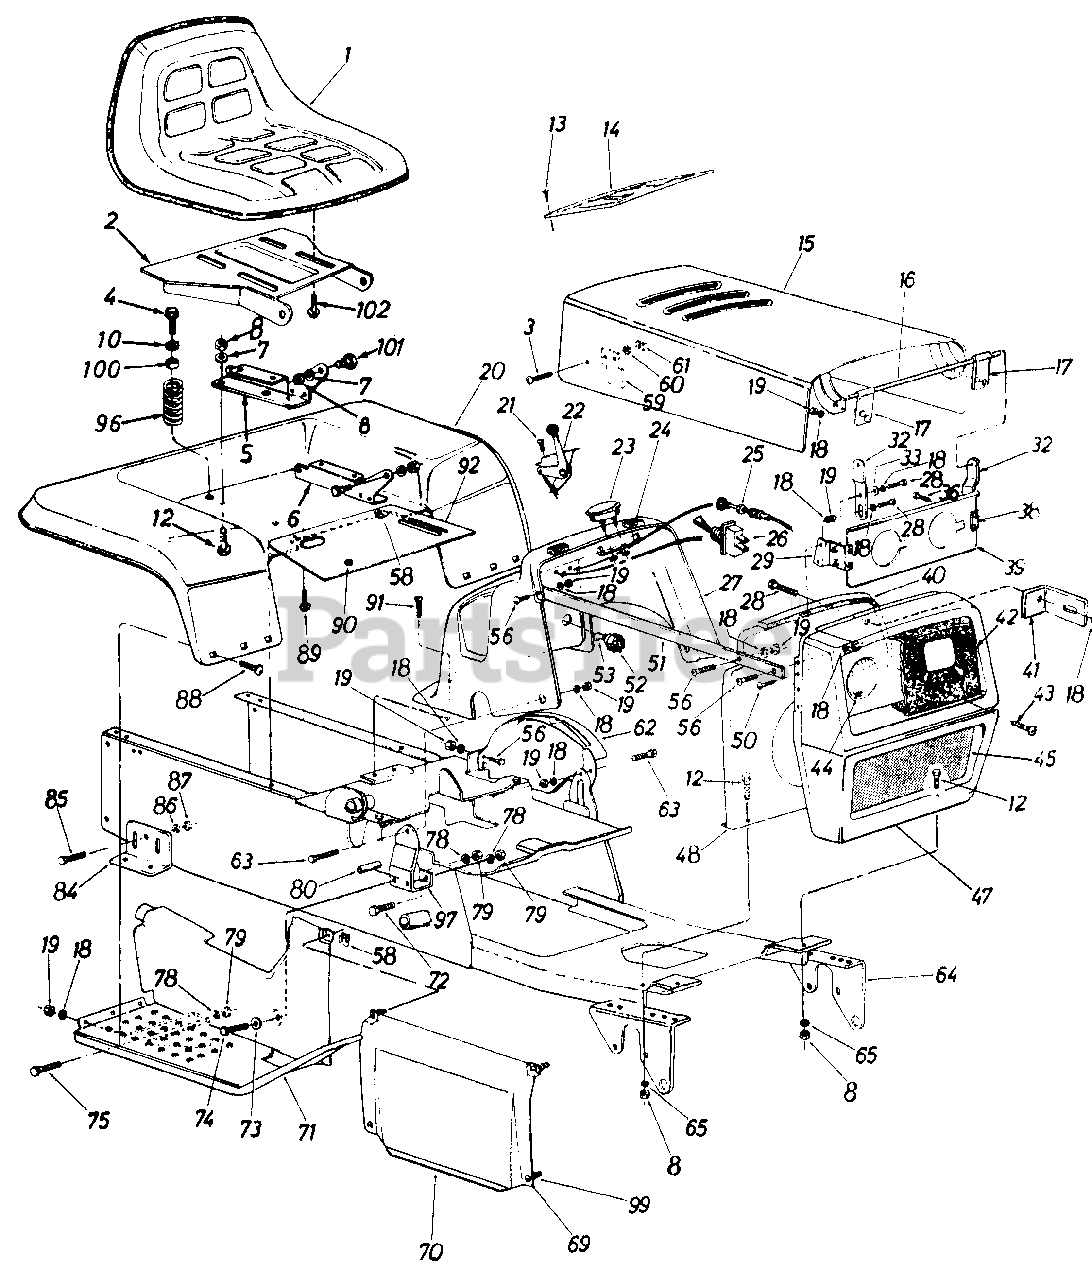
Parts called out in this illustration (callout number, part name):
1	Seat Ass'y.
2	Seat Pivot Brkt.
3	Truss Hd. Mach. Scr. #10-24 x .38" Lg.
4	Hex Wash. Hd. Self-Tap Scr. 5/16-18 x 1.75" Lg.
8	Hex Nut 5/16-18 Thd.
10	Fl-Wash 344" I.D. x .875" O.D
12	Hex Scr. 5/16-18 x .75" Lg.
13	Self-Tap Oval Hd. Scr. 1/2" Lg.
14	Dash Panel Cover
15	Hood Ass'y.
16	Hinge Rod
17	Hood Hinge Ass'y.
18	L-Wash. 1/4" I.D.
19	Hex Nut 1/4-20 Thd.*
20	Rear Fender
21	Fl-Hd. Truss Scr. #10 x .62" Lg.
22	Throttle Control
23	Ammeter
24	Rubber Bumper
25	Choke Control
26	Light Switch
27	Dash Panel
28	Hex Scr. 1/4-20 x .62" Lg.
29	Hood Support Brkt. Ass'y. R.H.
36	Hex Scr. 1/4-20 x .38" Lg.
38	Hood Support Brkt. Ass'y. L.H.
41	Heat Shield Brkt.
42	Head Lamp Bezel
43	Truss Mach. Scr. #10-24 x .50"
44	Head Lamp
45	Grille Screen
50	Truss Mach. Scr. 1/4-20 x .75" Lg.*
51	Grille Strap
52	Ignition Switch
53	Ignition Key
56	Hex Scr. 1/4-20 x .75/1 Lg.
58	Clip-On Receptacle
59	Hood Spring
60	L-Wash. #10
61	Hex Nut #10-24
62	Speed Control Guide
63	Truss Mach. Scr. 1/4-20 x .75"Lg.
64	Frame Ass'y.
65	Bell-Wash. 5/16 I.D.
69	1/4-Turn Stud
70	Hood Lower Side Panel
71	Foot Step Panel Ass'y. R.H.
72	Hex Scr. 3/8-16 x 1.00" Lg.Grade 5
73	Fl-Wash. .385 I.D. x .62 O.D.
74	Hex Scr. 3/8-16 x 3.00 Lg.
75	Hex Scr. 3/8-16 x 1.00" Lg.Grade 5
78	L-Wash. 3/8 I.D.*
79	Hex Nut 3/8-16 Thd.
80	Spacer .375 I.D. x .62 O.D. x 2.00 Lg.
84	Transaxle Support Brkt.
85	Rd. Hd. Rib Neck Scr. 3/8-24
86	L-Wash. 3/8 Scr.
87	Hex Nut 3/8-24 Thd.
88	Carr. Bolt 1/4-20 x .50 Lg.
89	Carr. Bolt 5/16-18 x .62 Lg.
90	Snap Bushing
91	Fl-Hd. Self-Tap Scr. 1/4-20 x .62 Lg.
96	Compression Spring
100	Bushing
101	Shld. Bolt .437 Dia. x .268
102	Self-Tap Scr. 3/8-16 x .75 Lg.
